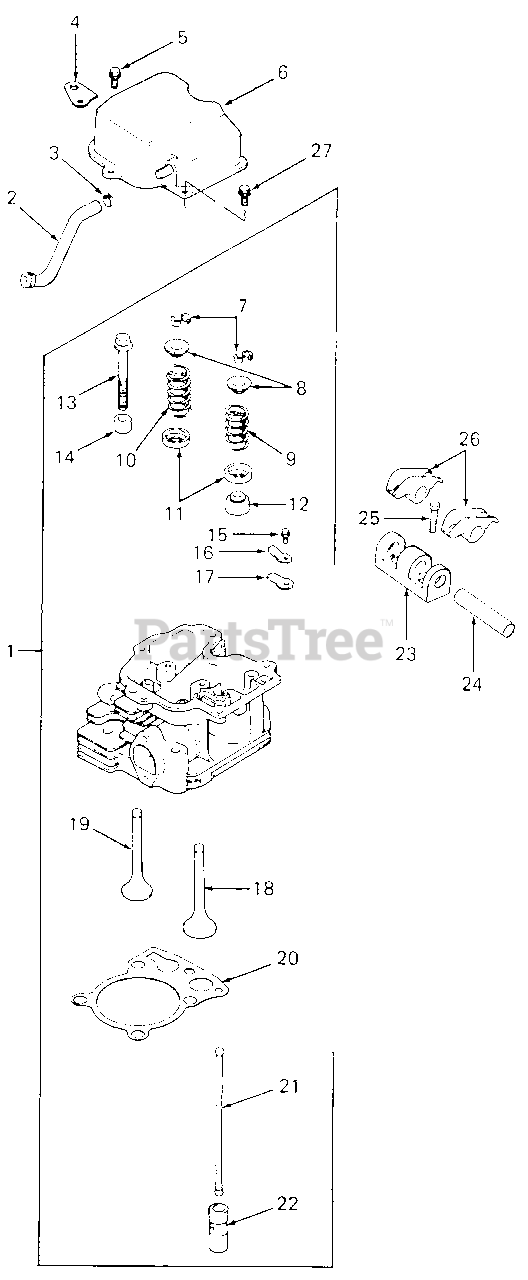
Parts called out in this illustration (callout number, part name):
1	Kit, Cylinder Head
2	Hose, Breather
3	Clamp, Hose
4	Strap, Lifting
5	Screw, Valve Cover, M6 X 1.0 X 25
6	Cover, Valve w/Nipple
7	Kit, Retainer
8	Cap, Valve Spring
9	Spring, Intake Valve
10	Spring, Exhaust Valve
11	Retainer, Spring
12	Seal, Valve Stem
13	Screw, Cylinder Head, M10 X 1.5 X 80
14	Spacer, Head Bolt Exhaust Port
15	Screw, Breather Reed Retainer, M5 X 0.8 X 10
16	Retainer, Breather Reed
17	Reed, Breather
18	Valve, Intake, Std
19	Valve, Exhaust, Std
20	Gasket, Cylinder Head
21	Rod, Push
22	Lifter, Valve
23	Bridge, Rocker Arm
24	Shaft, Rocker Arm
25	Screw, Rocker Bridge, M6 X 1.0 X 25
27	Screw, Valve Cover, M6 X 1.0 X 20
